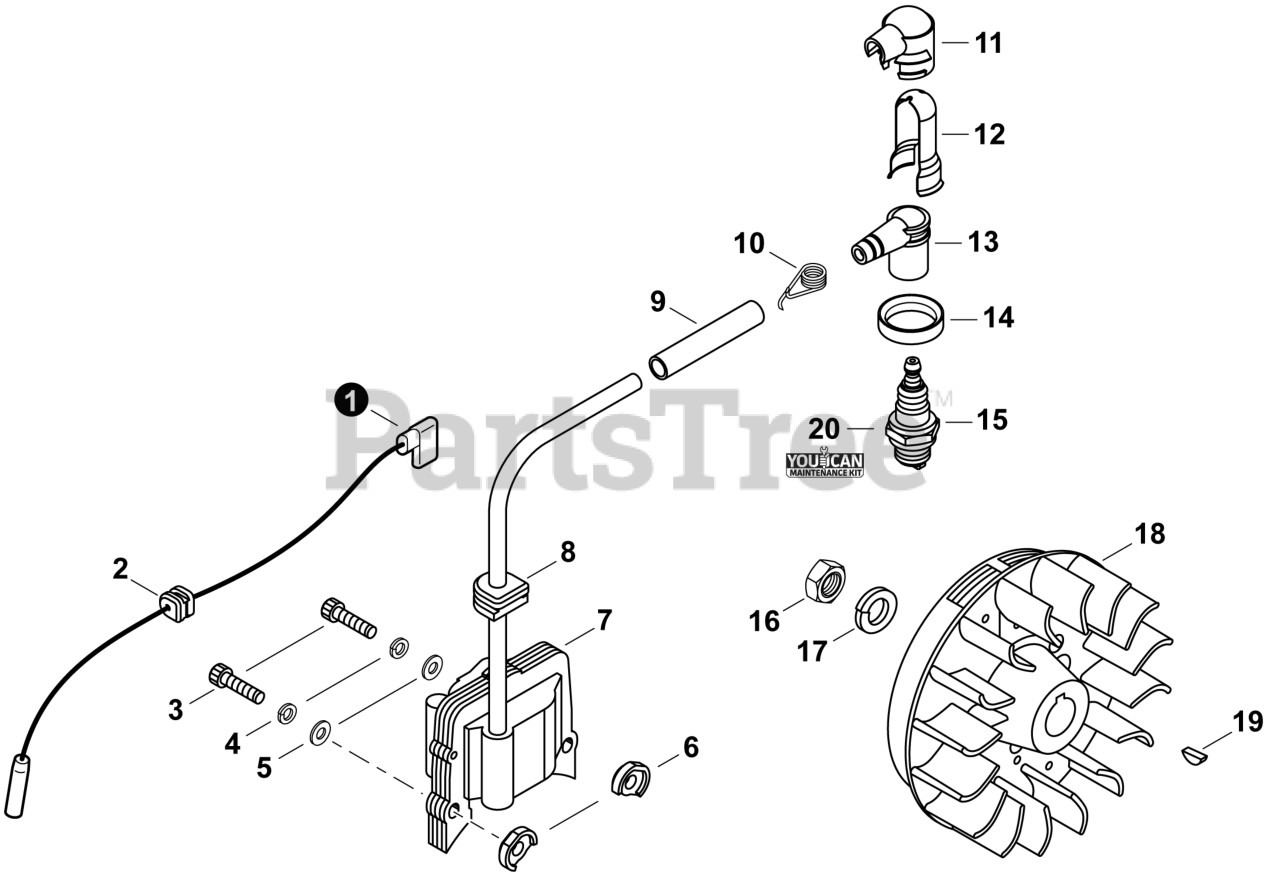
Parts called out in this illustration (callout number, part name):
1	LEAD - IGNITION
2	GROMMET, LEAD
3	BOLT M4x24
4	WASHER, SPRING 4
5	WASHER 4.3x9.6x0.8
6	COLLAR 4
7	COIL, IGNITION
8	GROMMET
9	TUBE, INSULATOR
10	TERMINAL, SPARK PLUG
11	COVER, CAP
12	SHIELD, SPARK PLUG
13	CAP, SPARK PLUG
14	SEAL, SPARK PLUG
15	SPARK PLUG - BMR6A
16	NUT 10x1.25
18	FLYWHEEL
19	KEY, WOODRUFF 3x10
20	TUNE-UP KIT - YOUCANT
